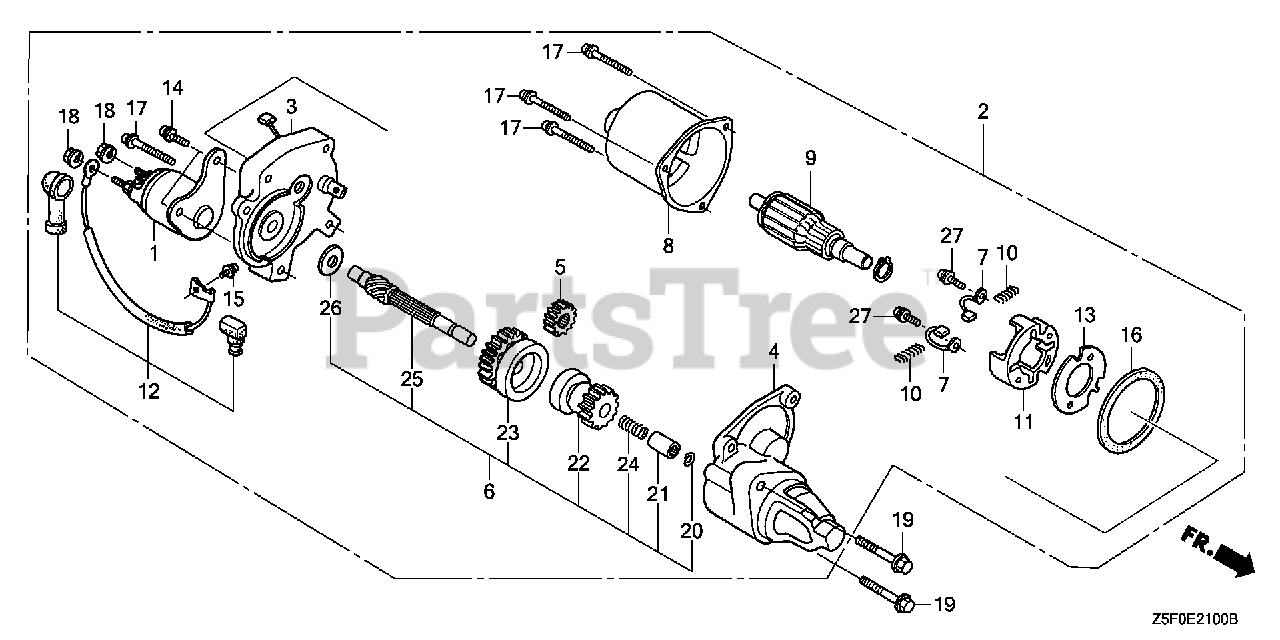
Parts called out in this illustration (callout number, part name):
1	CONTACTOR ASSY.
2	MOTOR UNIT, STARTER
3	BRACKET, CENTER
4	BRACKET, FR.
5	GEAR, DRIVE PINION
6	CLUTCH, OVERRUNNING
7	BRUSH
8	YOKE
9	ARMATURE
10	SPRING, BRUSH RETURN
11	HOLDER, BRUSH
12	WIRE, WATER COVER
13	INSULATOR
14	BOLT-WASHER (5X14)
15	SCREW-WASHER (4X6)
16	GASKET
17	SCREW-WASHER (5X3)
18	NUT-WASHER (6MM)
19	BOLT, FLANGE (8X40) Use up to Engine SN 1003236.
27	SCREW-WASHER (4X14)
